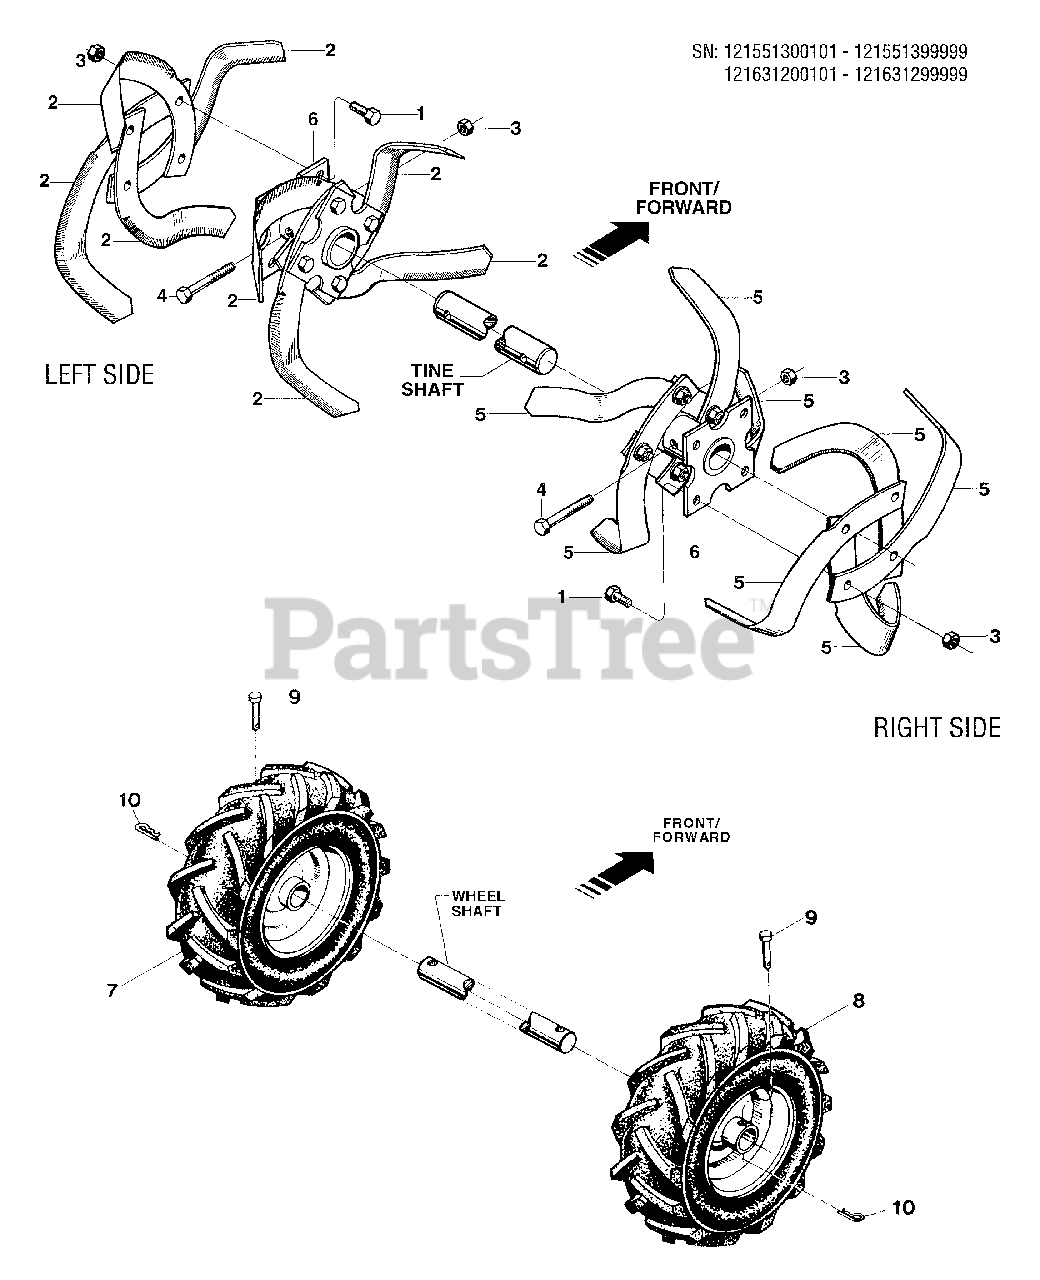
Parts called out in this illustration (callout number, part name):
1	Bolt-Hex Head, 3/8-16 x 1", Grade 5, Tine Mounting
2	Bolo Tine-Single, Right Hand tine used on left side of tiller
3	Locknut-Hex Hd., 3/8-16
4	Bolt-Hex Hd., 3/8-16 x 1-3/4" (tine holder to tiller shaft)
5	Bolo Tine-Single, Left Hand tine used on right side of tiller
6	Tine Holder-for bolo tines, left and right sides
7	Wheel & Tire Assy-Left Side
8	Wheel & Tire Assy-Right Side
9	Clevis Pin-.312" x 1-3/4", secures wheel hub to wheel shaft
10	Hair Pin Cotter
